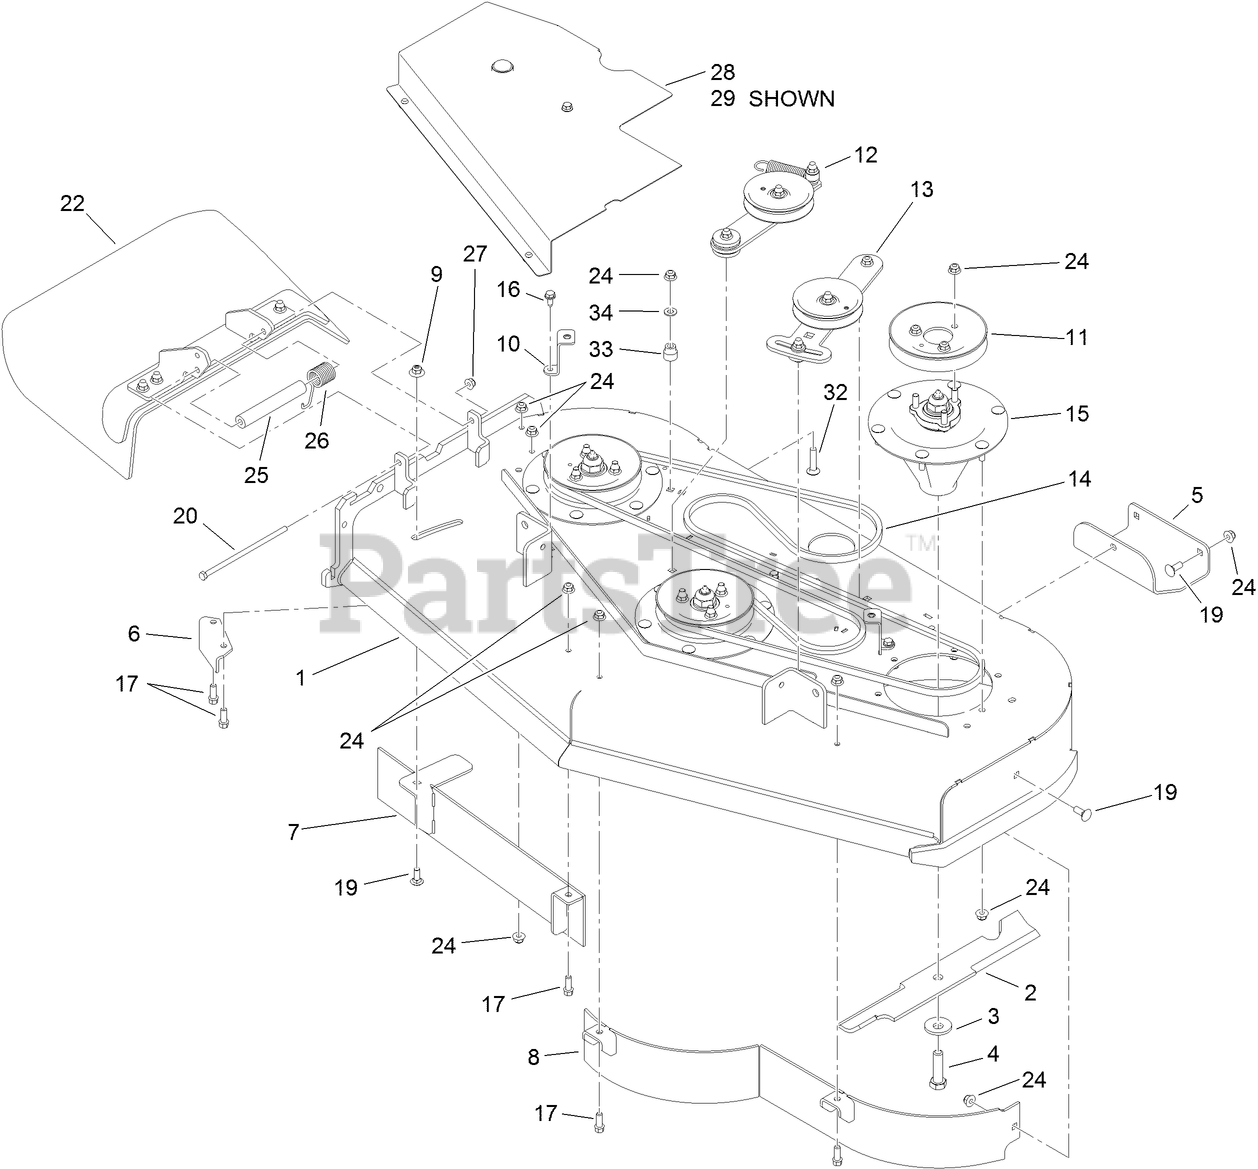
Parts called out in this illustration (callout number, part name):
1	DECK ASM
2	BLADE-16.5 INCH (HIGH FLOW)
3	Washer-Blade Bolt, Heavy
4	SCREW-BLADE
6	BAFFLE-DISCHARGE
8	48 INCH BAFFLE ASM
9	NUT-FLANGE, NI
10	BELT COVER BRACKET ASM
11	PULLEY
12	IDLER ARM ASM
13	IDLER ADJUST ASM
14	BELT-V
15	SPINDLE ASM
16	SCREW-HWHTF
17	SCREW-HWH
19	BOLT-CARR
20	SCREW-HH
22	DEFLECTOR ASM
24	NUT-HF, NI
25	SPACER
26	SPRING-TORSION
27	NUT-HF, NI
28	LH BELT COVER ASM
29	RH BELT COVER ASM
32	SCREW-CARR
33	BUSHING-IDLER
34	WASHER-FLAT
